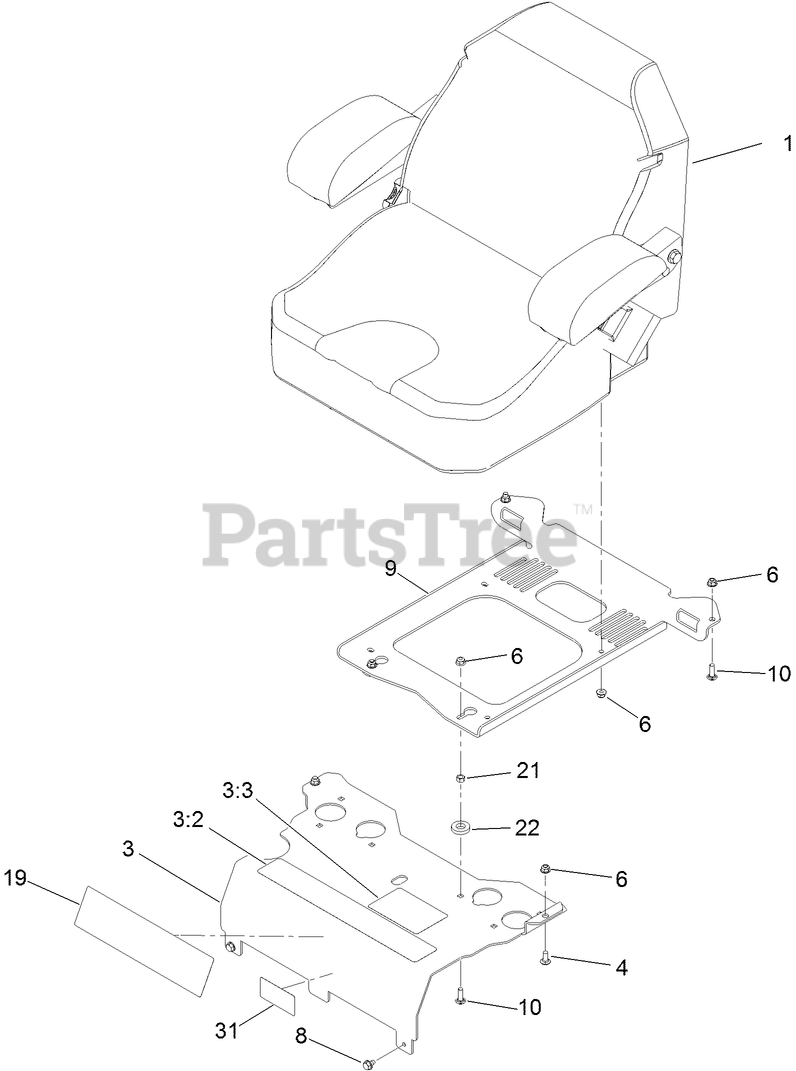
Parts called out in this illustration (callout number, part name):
1	SEAT ASM
3	MOUNT-SEAT
3:2	DECAL-CONSOLE
3:3	DECAL-SERVICE AID
4	SCREW-CARR
6	NUT-HF, NI
8	SCREW
9	PLATE-SUPPORT, SEAT
10	SCREW-CARR
21	NUT-HEX
22	SPACER
31	DECAL-EFI
